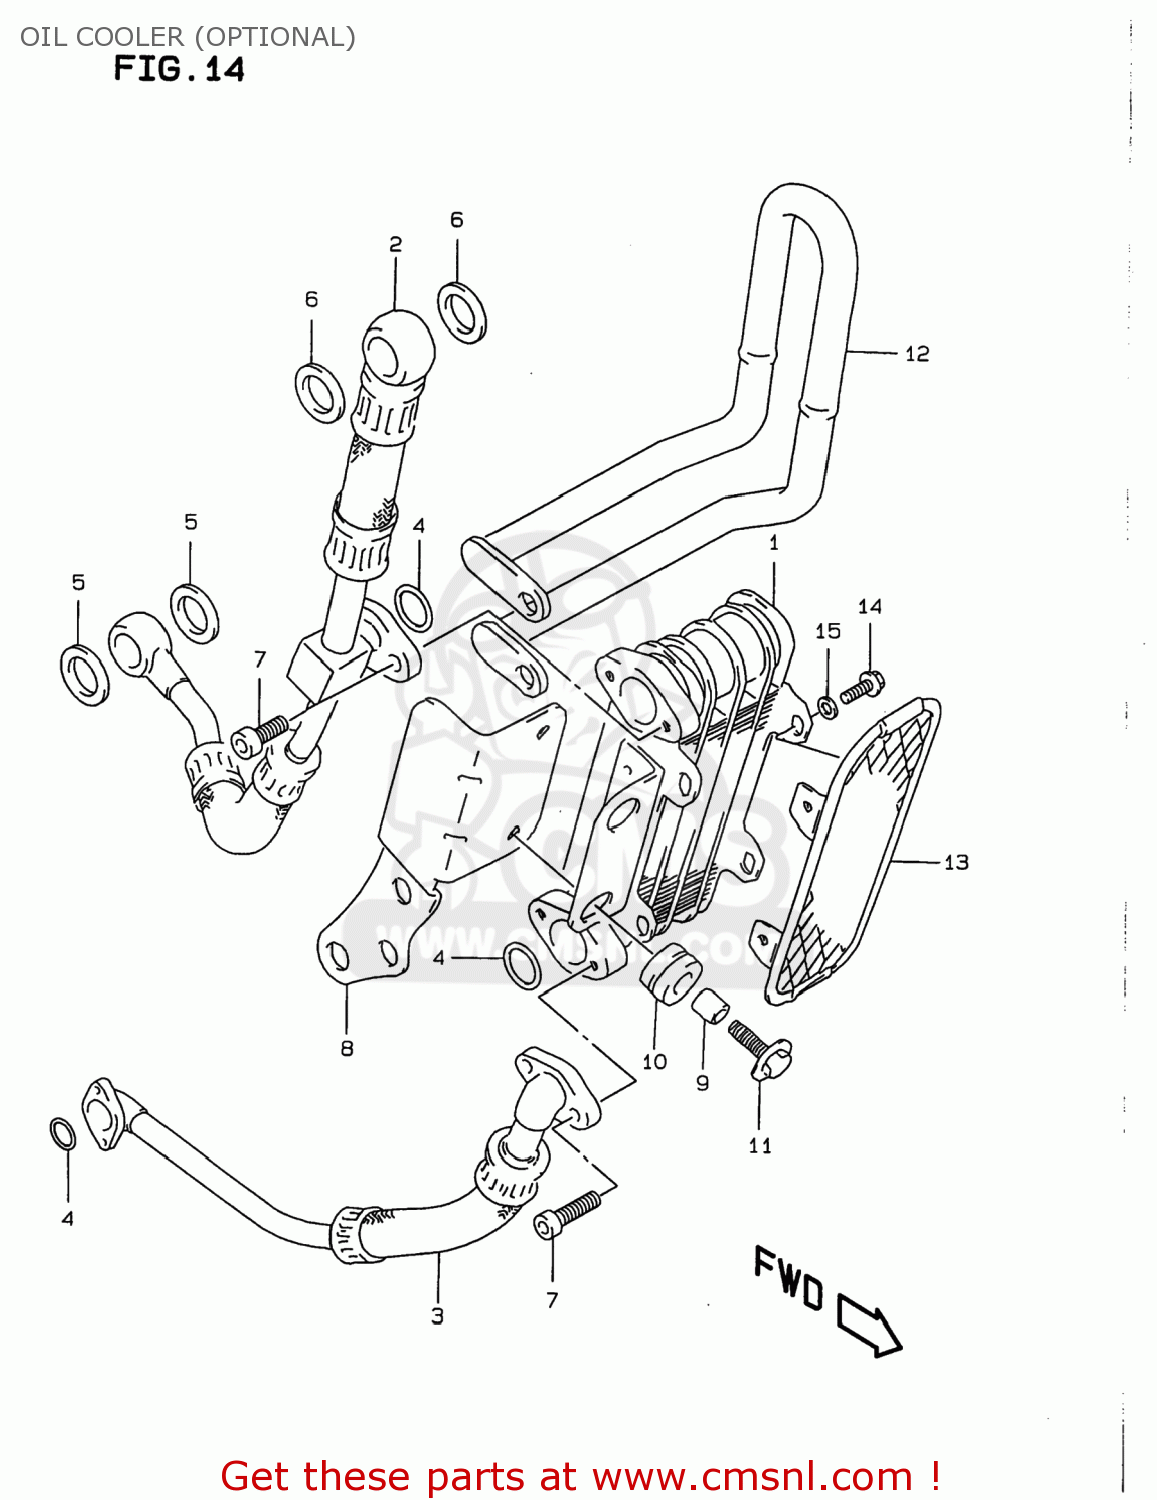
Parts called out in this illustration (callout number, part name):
1	COOLER ASSY,OIL
2	HOSE,OIL COOLER UPR
3	HOSE,OIL COOLER LWR
4	O RING(D:2.4,ID:12.3)
5	GASKET(12X17X1) (NAS)
6	GASKET(16X22X2) (NAS)
7	BOLT,OIL FILLE
8	BRACKET,OIL COOLER
9	SPACER(6.5X10X10)
10	CUSHION
11	BOLT 6X20
12	GUARD,OIL COOLER
13	BUMPER,OIL COOLER
14	BOLT
15	LOCK,WASHER
